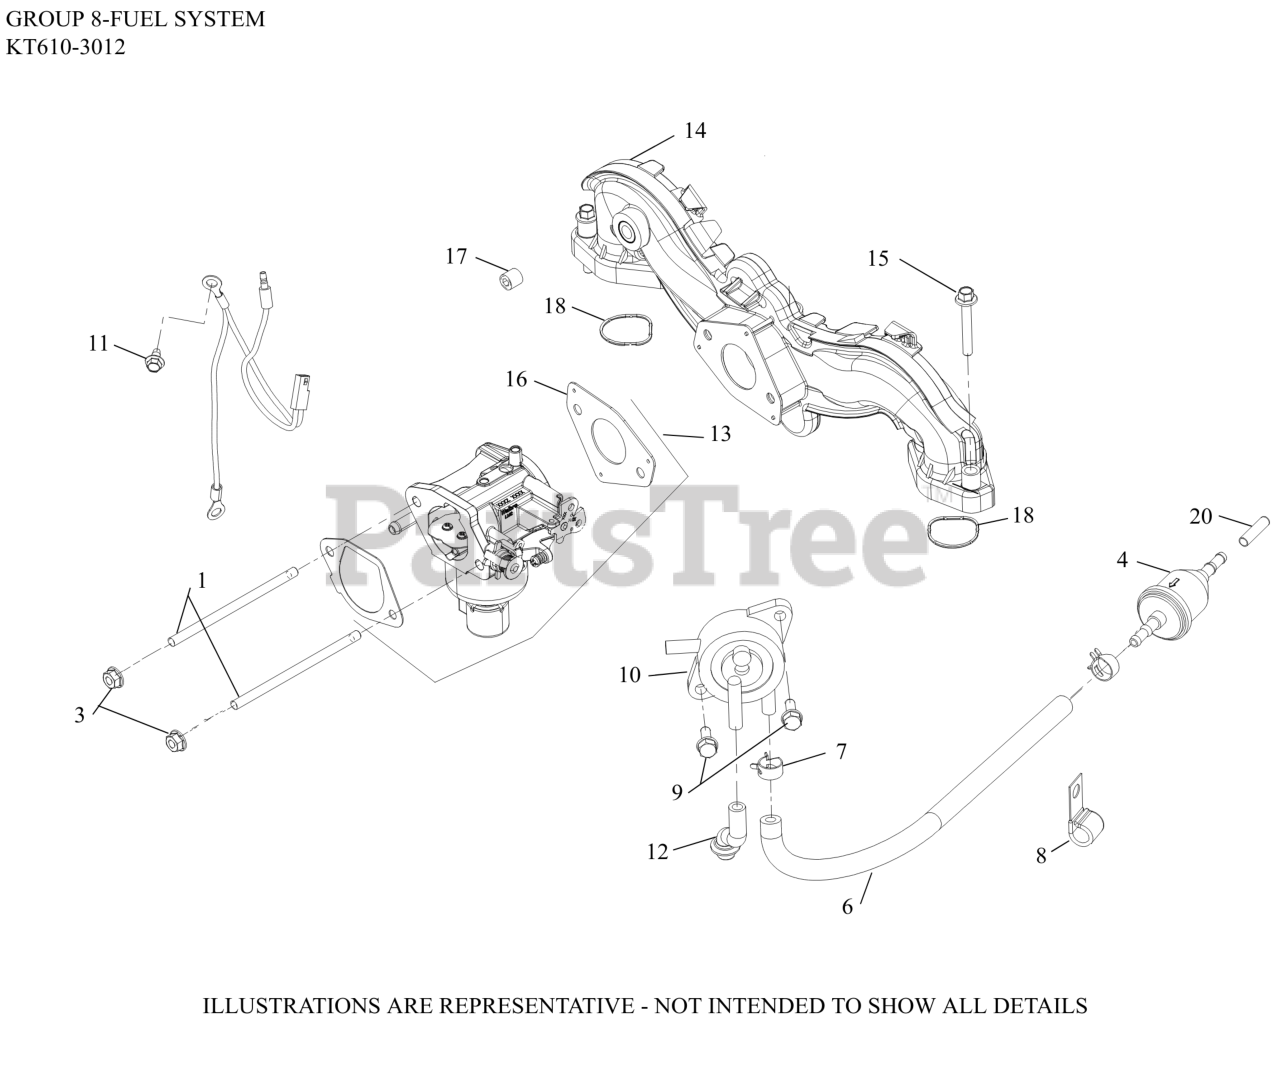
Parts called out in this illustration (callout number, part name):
3	NUT, FLG M6X1.0
4	FILTER,FUEL 51 MICRON (FUEL PUMP)
6	HOSE,LW PERM.FUEL 24.00"-USE 25 111 81-S
7	SPRING CLAMP, HOSE
8	CLIP, CABLE
9	SCREW, TAP M6X1.7X18
10	PUMP, FUEL (PULSE)-(#2539326S)
11	SCREW, THREAD FORMING
12	HOSE, PULSE PUMP(STEEL COVERS)
13	KIT,CARB(WALBRO)
14	KIT, INTAKE MANIFOLD-(#24164277S)
15	SCREW, FLG M6X1.0X40
16	GASKET, CARBURETOR
17	PLUG, CTSK PIPE 1/8"
18	O-RING, INTAKE PORT (PIM)
NI	KIT,REPAIR OVERHAUL(WALBRO)
NI	KIT,BOWL O-RING(WALBRO)
NI	KIT, HI ALTITUDE (5000 FT) 19MM
NI	KIT,SOLENOID REPAIR(WALBRO)
NI	KIT,REPAIR FLOAT(WALBRO)
